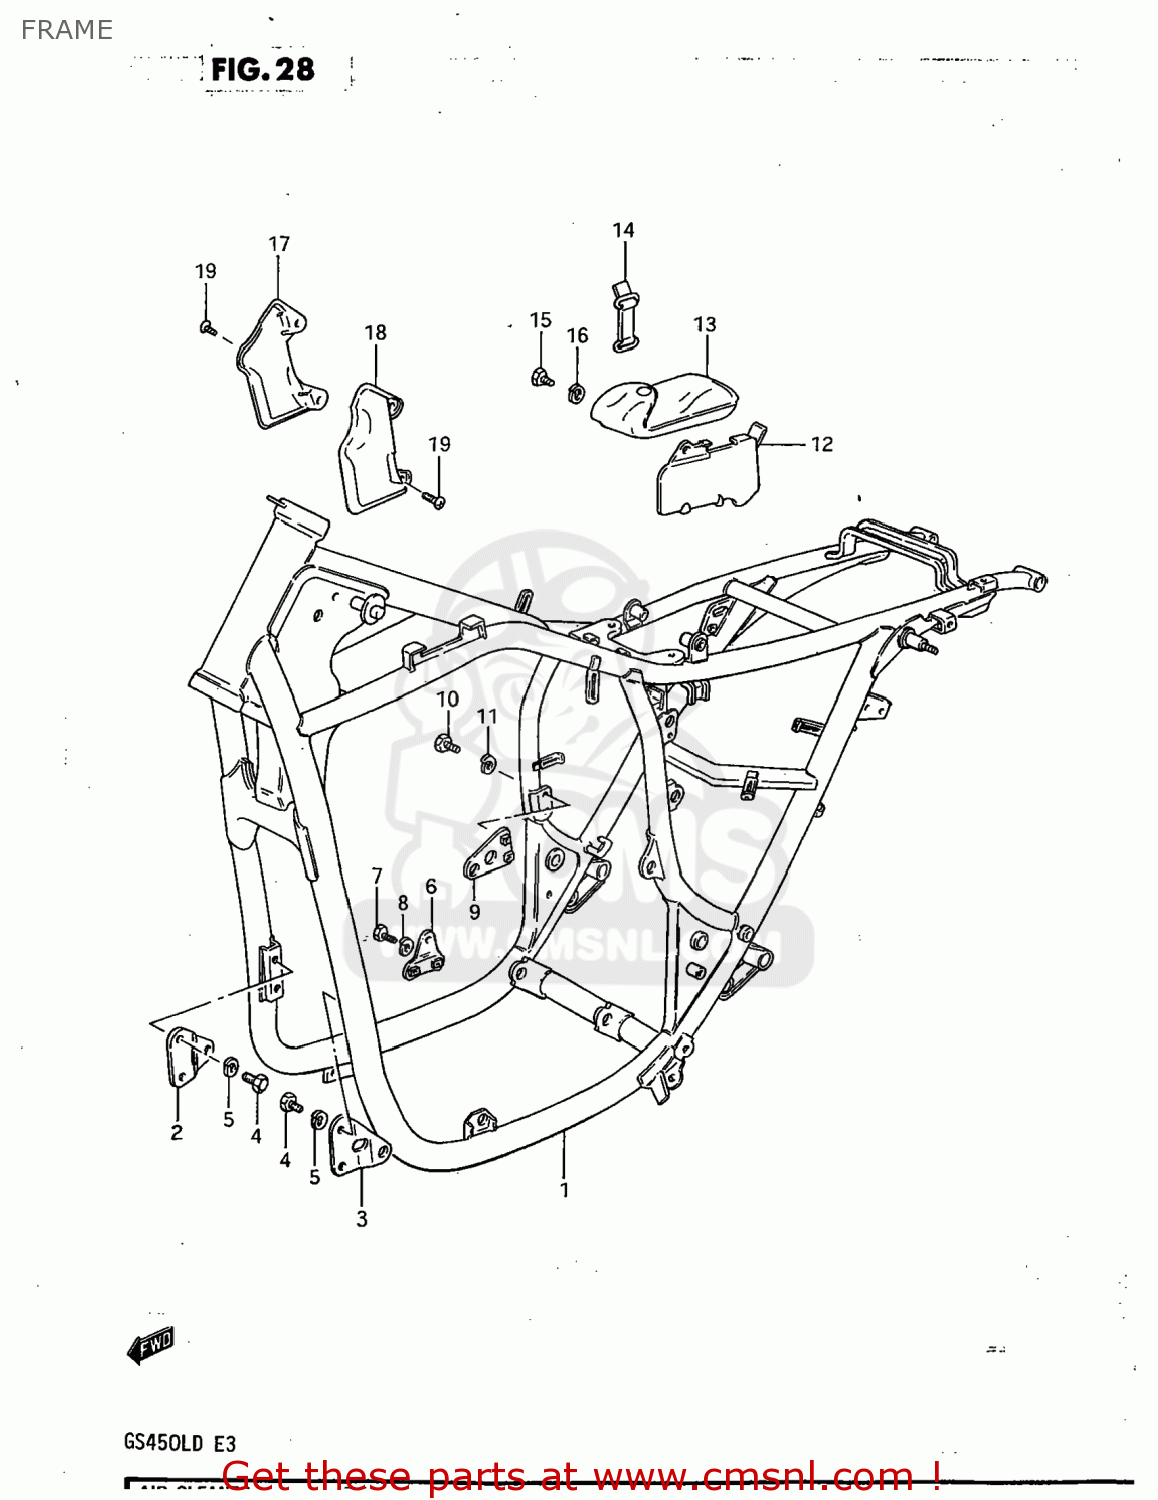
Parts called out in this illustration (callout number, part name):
1	FRAME
2	PLATE,ENG MTG NO.1,R
3	PLATE,ENGINE MOUNTING,LEFT
4	BOLT
5	LOCK WASHER
6	PLATE,MOUNTING NO.2,LEFT
7	BOLT
8	LOCK WASHER
9	PLATE,MOUNTING NO.4,LEFT
10	BOLT
11	LOCK WASHER
12	HOLDER,TOOL
13	TOOL SET
14	BAND
15	BOLT
16	LOCK WASHER
17	COVER,FRAME HEAD,RIGHT
18	COVER,FRAME HEAD,LEFT
19	SCREW
